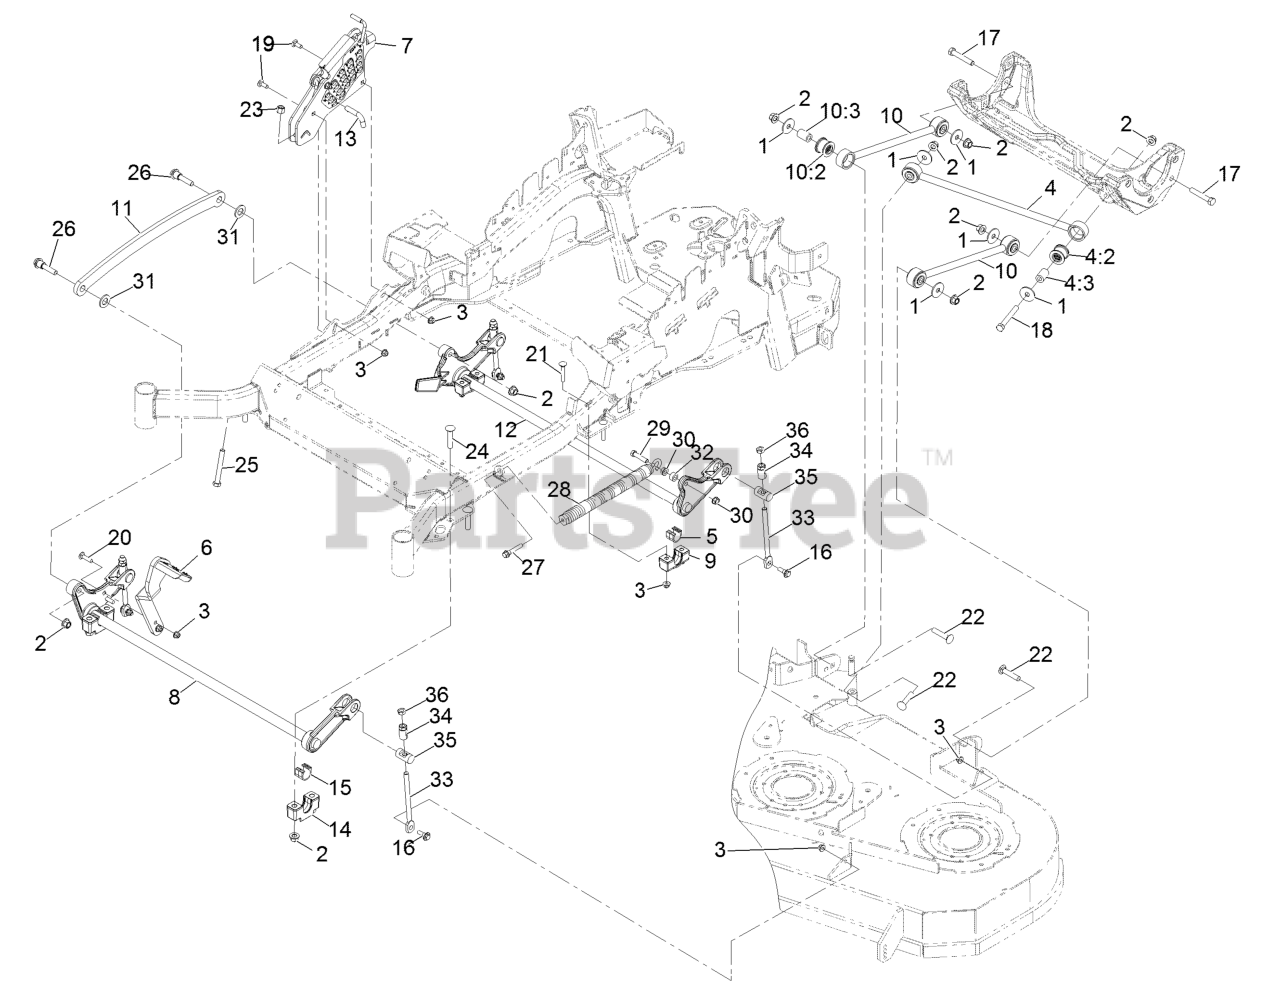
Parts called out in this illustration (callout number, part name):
2	Nut-Lock 1/2-13
3	Nut-Nyloc 3/8-16 Flg
4	Panhard Rod ASM
4:2	Bushing-Suspension,Rubber
5	Bearing-Cross Shaft, Rear
6	Lever-Foot
7	HOC ASM
8	Decklift-Front
9	Support-Cross Shaft,Bearing Rear
10	Deck Strut ASM
10:2	Bushing-Suspension,Rubber
11	Link-Lift, Deck
12	Lift-Deck, Rear
13	Pin-HOC
14	Support-Cross Shaft, Bearing
15	Bearing-Cross Shaft, Front
16	Screw-Hex Flange 3/8-16 X .80
17	Screw-HH 1/2-13 X 3
18	Screw-HH 1/2-13 X 4
19	Bolt-Carriage 3/8-16 X 1
20	Bolt-Carriage 3/8-16 X 1 1/2
21	Bolt-Carriage 3/8-16 X 2 1/4
22	Bolt-Carriage 1/2-13 X 2 1/2
23	Nut-Nyloc 1/2-13
24	Bolt-Carriage 1/2-13 X 2 1/2 Spl Neck
25	Bolt-HH 1/2-13 X 4 Tap
26	Screw-Hex Flange 1/2-13 X 1.90
27	Screw-Shcs 3/8-16 X 2.212
28	Spring-Extension
29	Screw-HH 7/16-14 X 2
30	Nut-Whizlock 7/16-14
31	Washer-3/4 SAE
33	Link-Adjuster, Deck Lift
34	Adjuster-Lift, Deck
35	Trunnion
36	Nut-Jam 1/2-13
